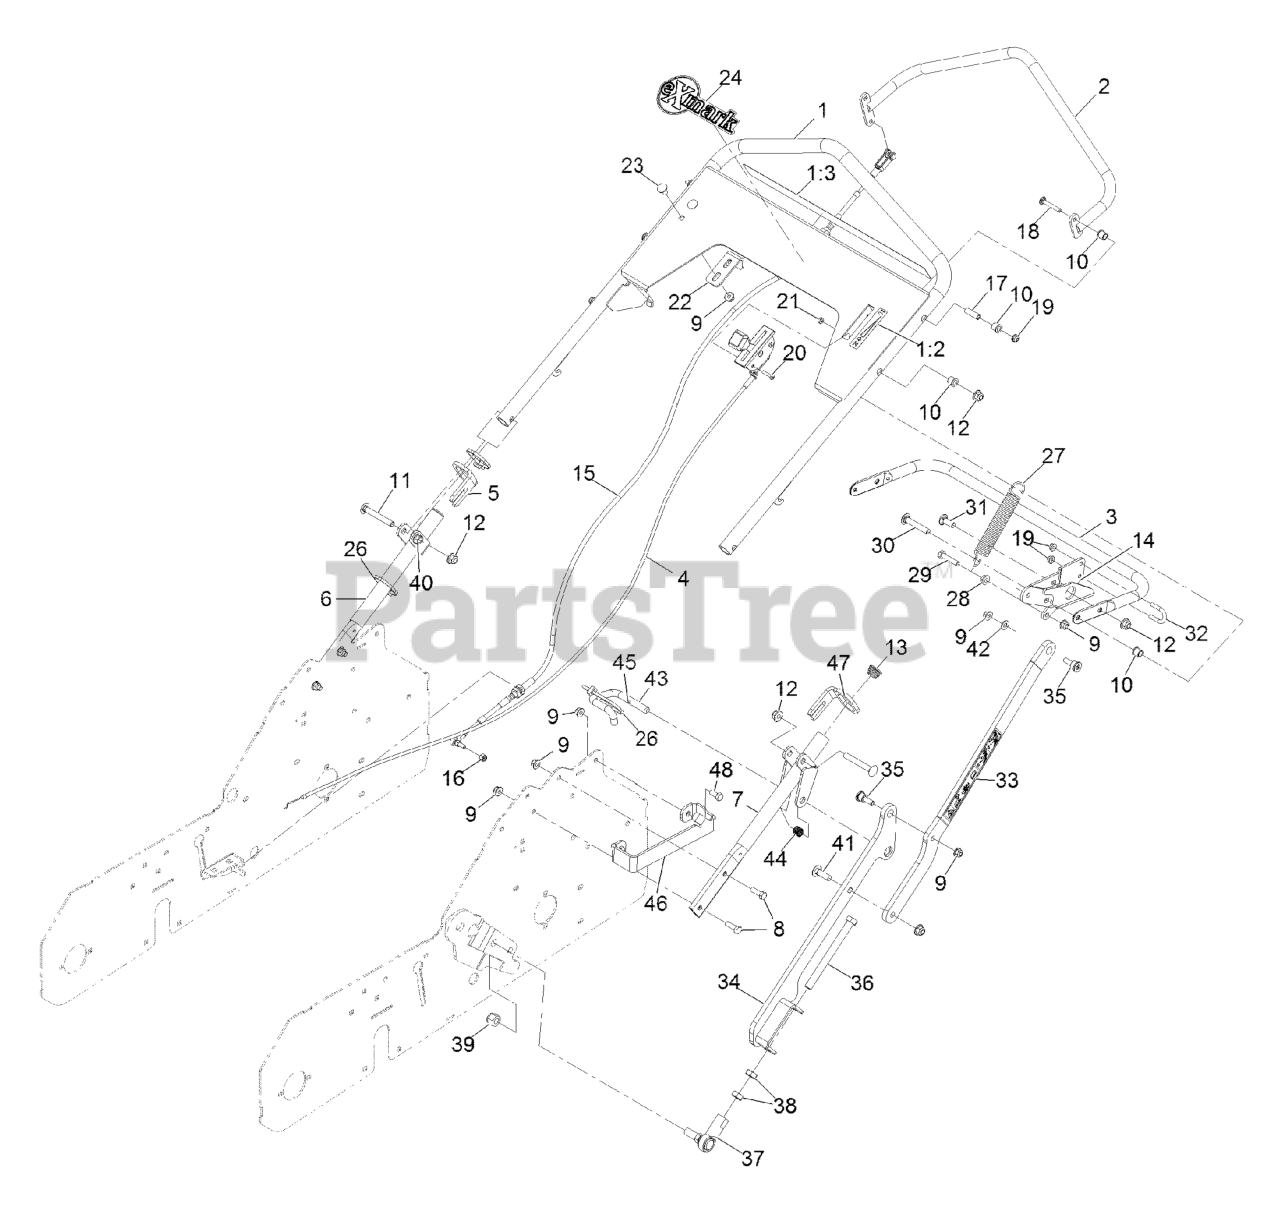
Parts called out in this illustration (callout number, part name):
1	HANDLE ASM
1:2	DECAL-THROTTLE, CHOKE
1:3	DECAL-AERATOR CONTROL PAN
2	TUBE-CONTROL
3	TUBE-HANDLE LIFT
4	CONTROL-THROTTLE
5	RING, HANDLE LOCK
6	HANDLE-LOWER
7	HANDLE-LOWER, LH
8	SCREW-HH
9	NUT-HF, NI
10	BEARING
11	SCREW-CARR
12	NUT-HF, NI
14	ARM-UPPER
16	NUT-LOCK
17	BUSHING-PIVOT
18	SCREW-CARR
20	SCREW-PPH
21	NUT-LOCK, NI
22	ANGLE-STOP
23	SCREW-CARR
24	DECAL, EXMARK LOGO
26	TIE-CABLE
27	SPRING-EXTENSION
29	SCREW-HH
30	BOLT-CARR, SHORT NECK
31	SCREW-CARR
33	ASM, UPPER LINK W/ DECAL
34	ARM-LOWER
35	BOLT-SHOULDER, GROOMER
36	SCREW, HH
37	END-ROD, RH THREAD
38	NUT-JAM
39	NUT-HEX
40	NUT-HHF, WHIZ
41	BOLT-CARR
42	WASHER-PLAIN
43	PIN-LATCH, TRANPORT
44	SPRING-COMPRESSION
45	PIN-SPRING
46	STRAP, STOP
47	RING, HANDLE LOCK
48	SCREW-HH
